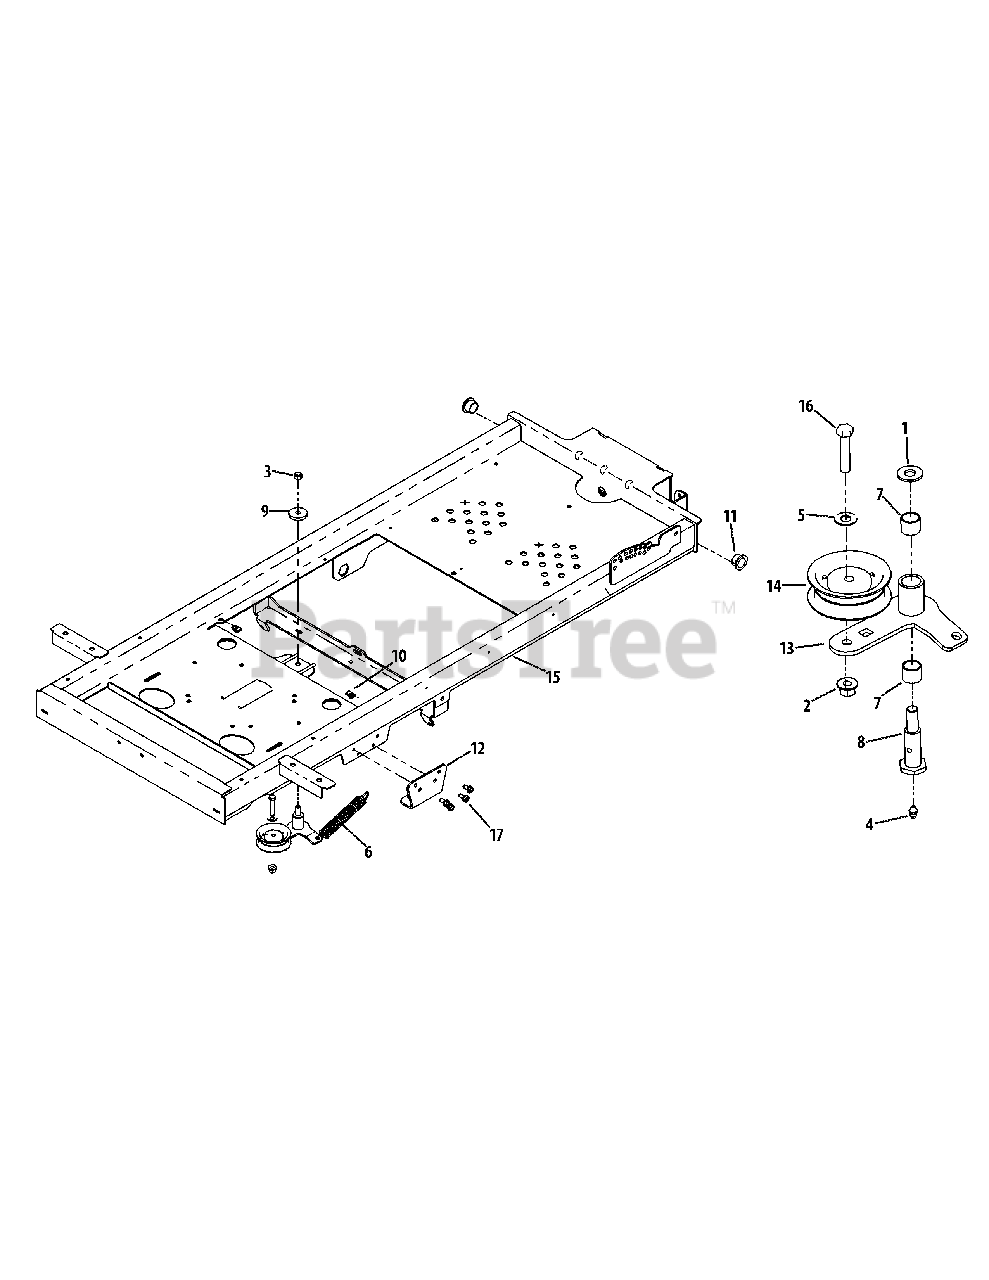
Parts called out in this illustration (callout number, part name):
1	Flat Washer, 3.8
2	Flange Lock Nut, 3.8-16
3	Nylock Nut, 7.16-14
4	Grease Fitting, 1.4-28 x 3.16
5	Washer, 3.8
6	Extension Spring, 1.00 x 5.00
7	Bearing Sleeve
8	Shoulder Bolt
9	Flat Washer, 7.16 x 1.75
10	U-Nut, 1.4-20
11	Bronze Bushing, 1.00 ID x 1.50 OD
12	Transmission Mounting Bracket
13	Idler Arm
14	Flat Idler Pully
15	Frame Assembly
16	Hex Cap Screw, 3.8-16 x 1-3.4
17	Self Tapping Screw, 5.16-18 x .750
